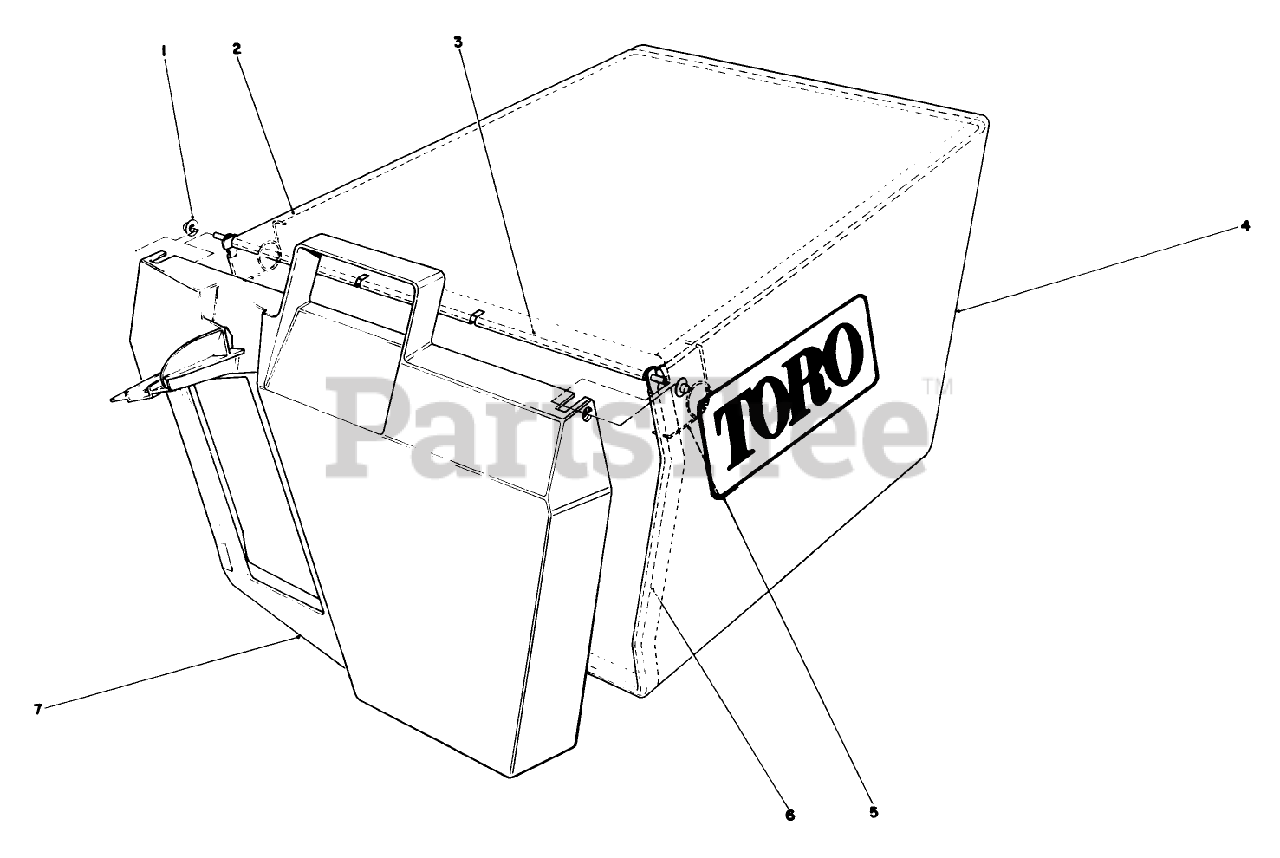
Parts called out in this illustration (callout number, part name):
1	NUT-PUSH
3	HINGE-DOOR, BAG
5	SPRING
7	BAG DOOR
